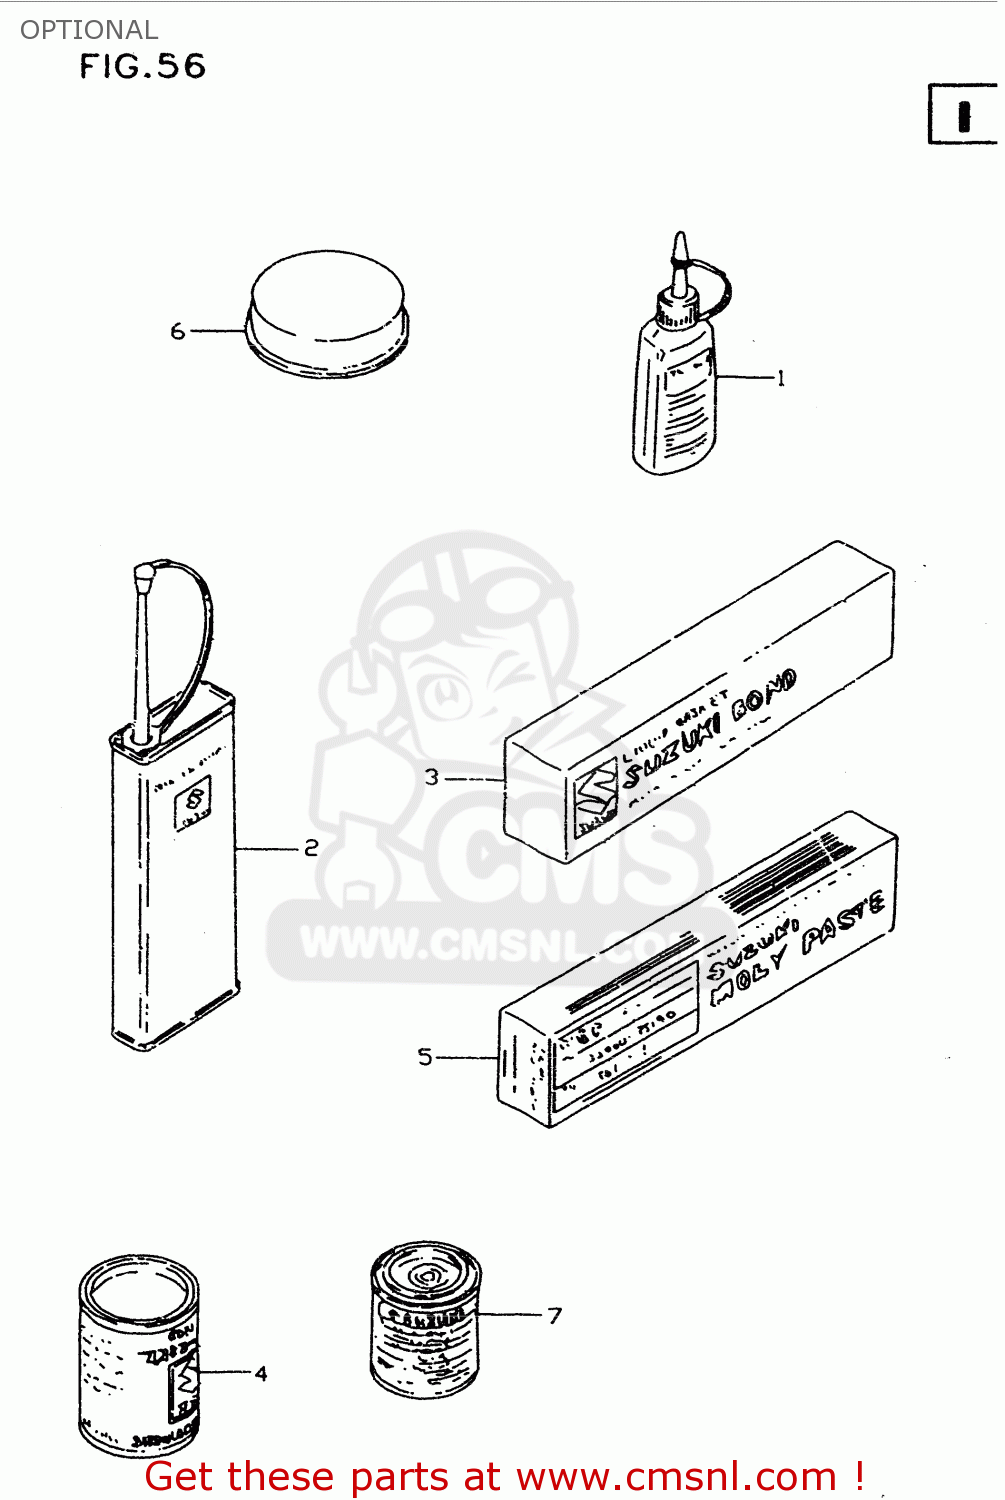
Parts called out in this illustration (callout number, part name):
1	THREAD LOCK NO.1342
2	THREAD LOCK NO.1401 CLEAR 200G
3	LIQUID GSKT NO.1215 250G
4	GREASE(C)EP2 LITHIUM 150G
5	SUZUKI MOLY PASTE
6	GREASE,PBC FOR BRK PAD 20G
7	PAINT,BLACK
